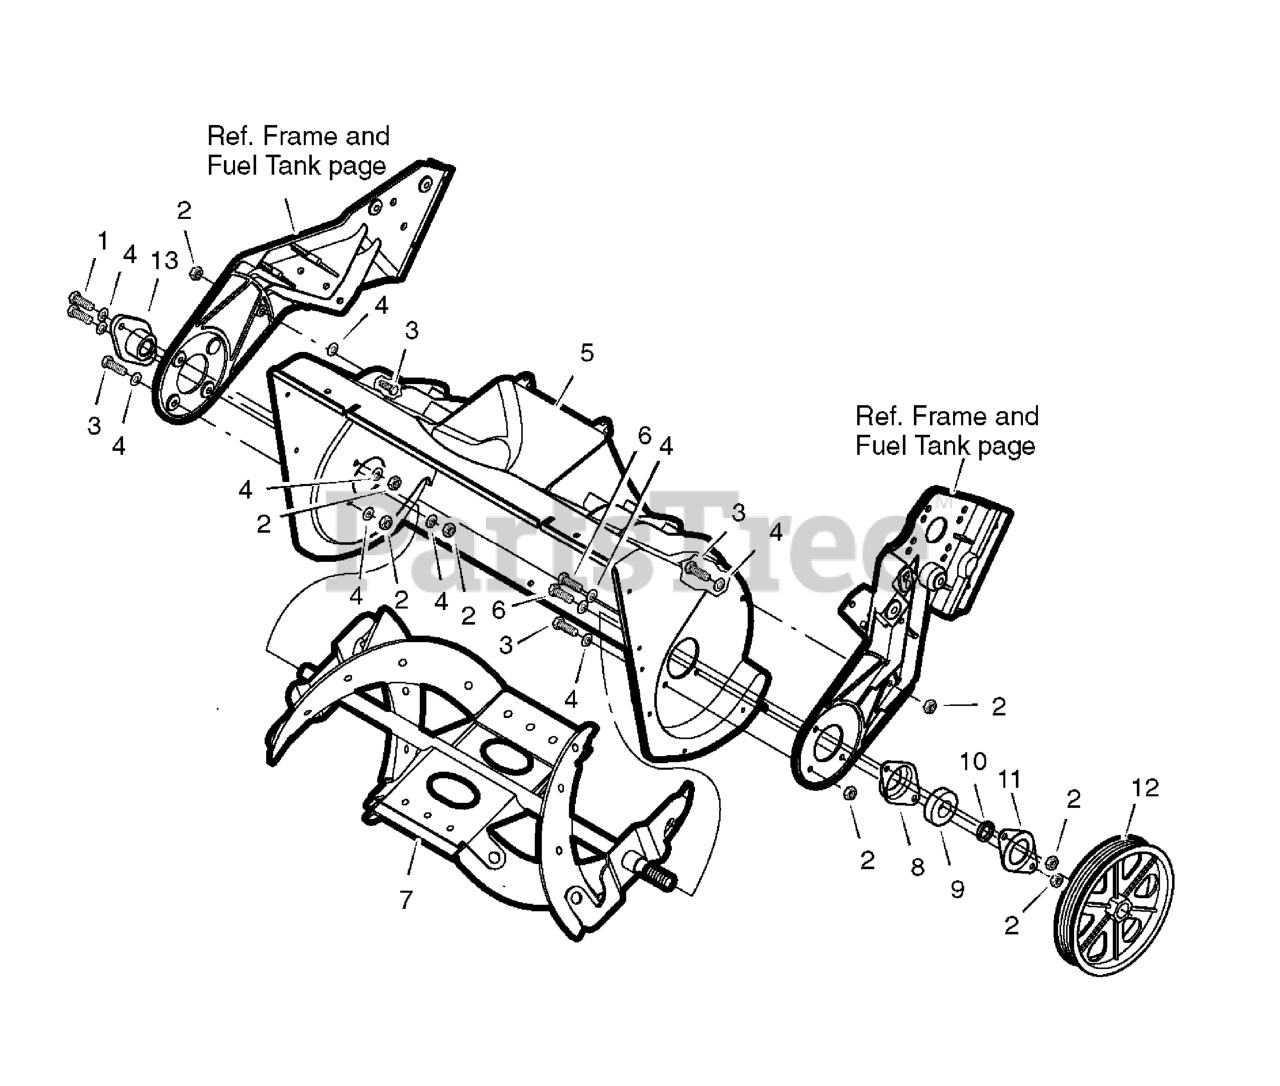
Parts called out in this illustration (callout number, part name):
1	Screw 1/4-20 x 1.00
2	Nut, Hex 1/4-20
3	Screw, 1/4-20 x .75
4	Washer, Flat
5	Housing Assy, Auger
6	Screw, 1/4-20 x .63
7	Auger Assembly, 22"
8	Retainer, Bearing
9	Bearing
10	Sleeve, Spacer
11	Plate, Bearing Retainer
12	Pulley, Auger Drive V6
13	Bearing, Flange
